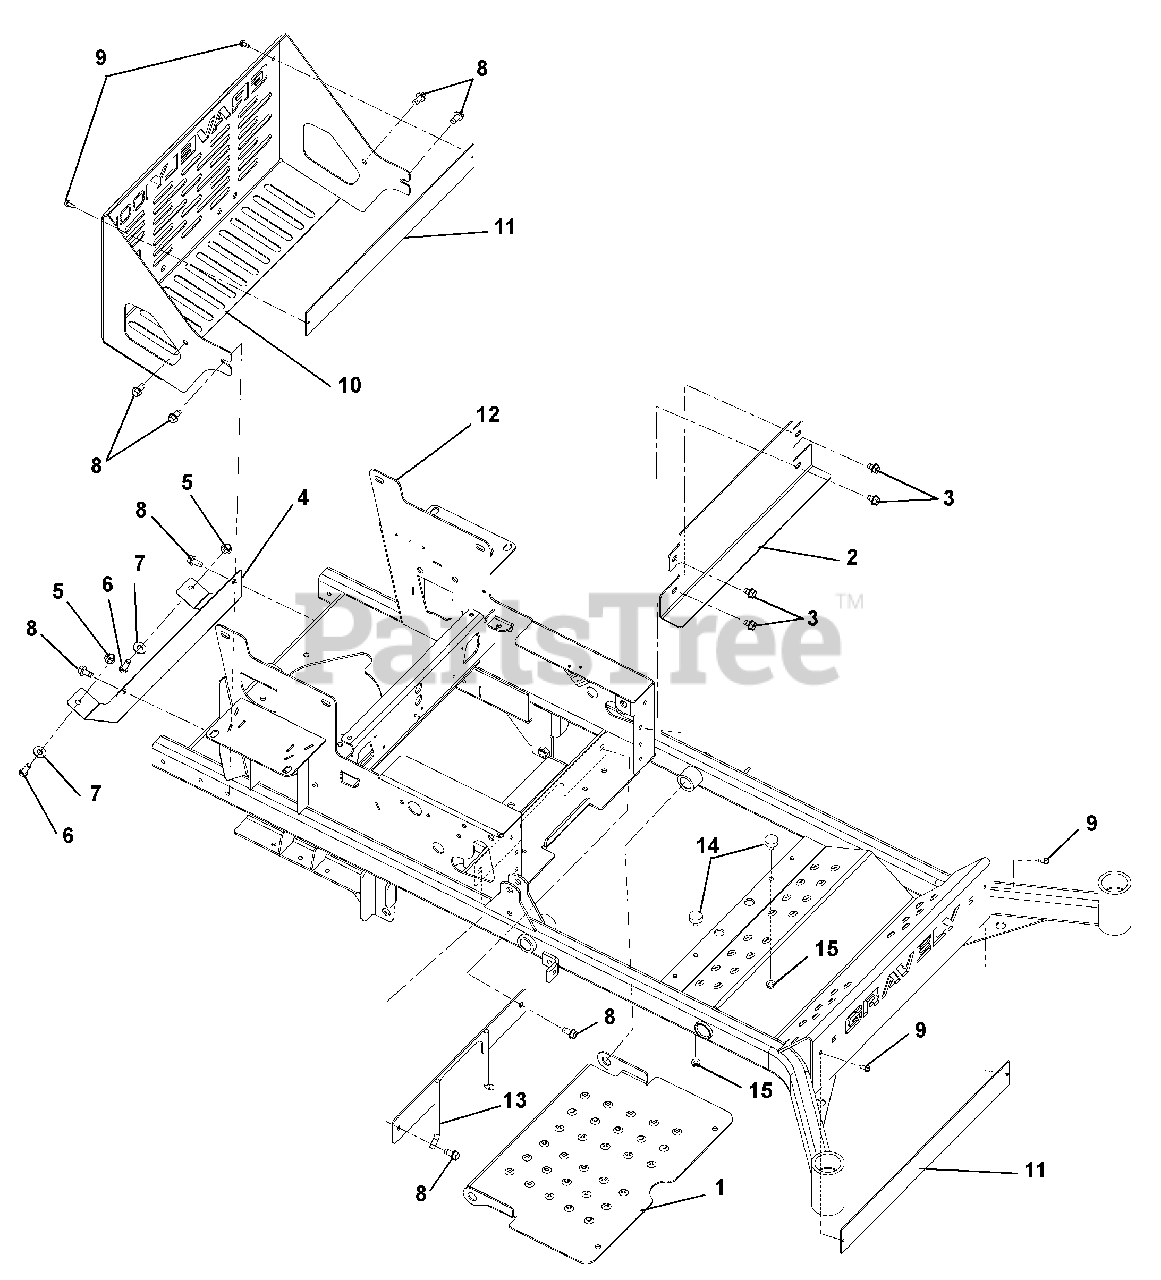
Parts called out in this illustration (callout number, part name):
1	100I Foot Plate
2	100I Kick Plate
3	Screw, Tapping .38-16 x .50 Hex Washer Head Thread Rolling
4	Shield, Heat- CZ PROD
5	Nut, .38-16 Nyloc Flange
6	Bolt, Hex .38-16X1.00 Grade 5
7	Washer, Flat-Steel .438 x 1.00 x .083
8	Screw, Tapping .38-16 x .75 Hex Washer Head Thread Rolling
9	Screw, Tapping .25-20 x .50 Hex Washer Head Thread Rolling
10	Gravely 100I Bumper
11	100I Bumper Name Back Plate
12	100I 60" Main Frame Weldment (064)
13	100I PTO Belt Finger Weldment
14	Bumper, Rubber
15	Nut, Spin Lock-Flange .312-18
